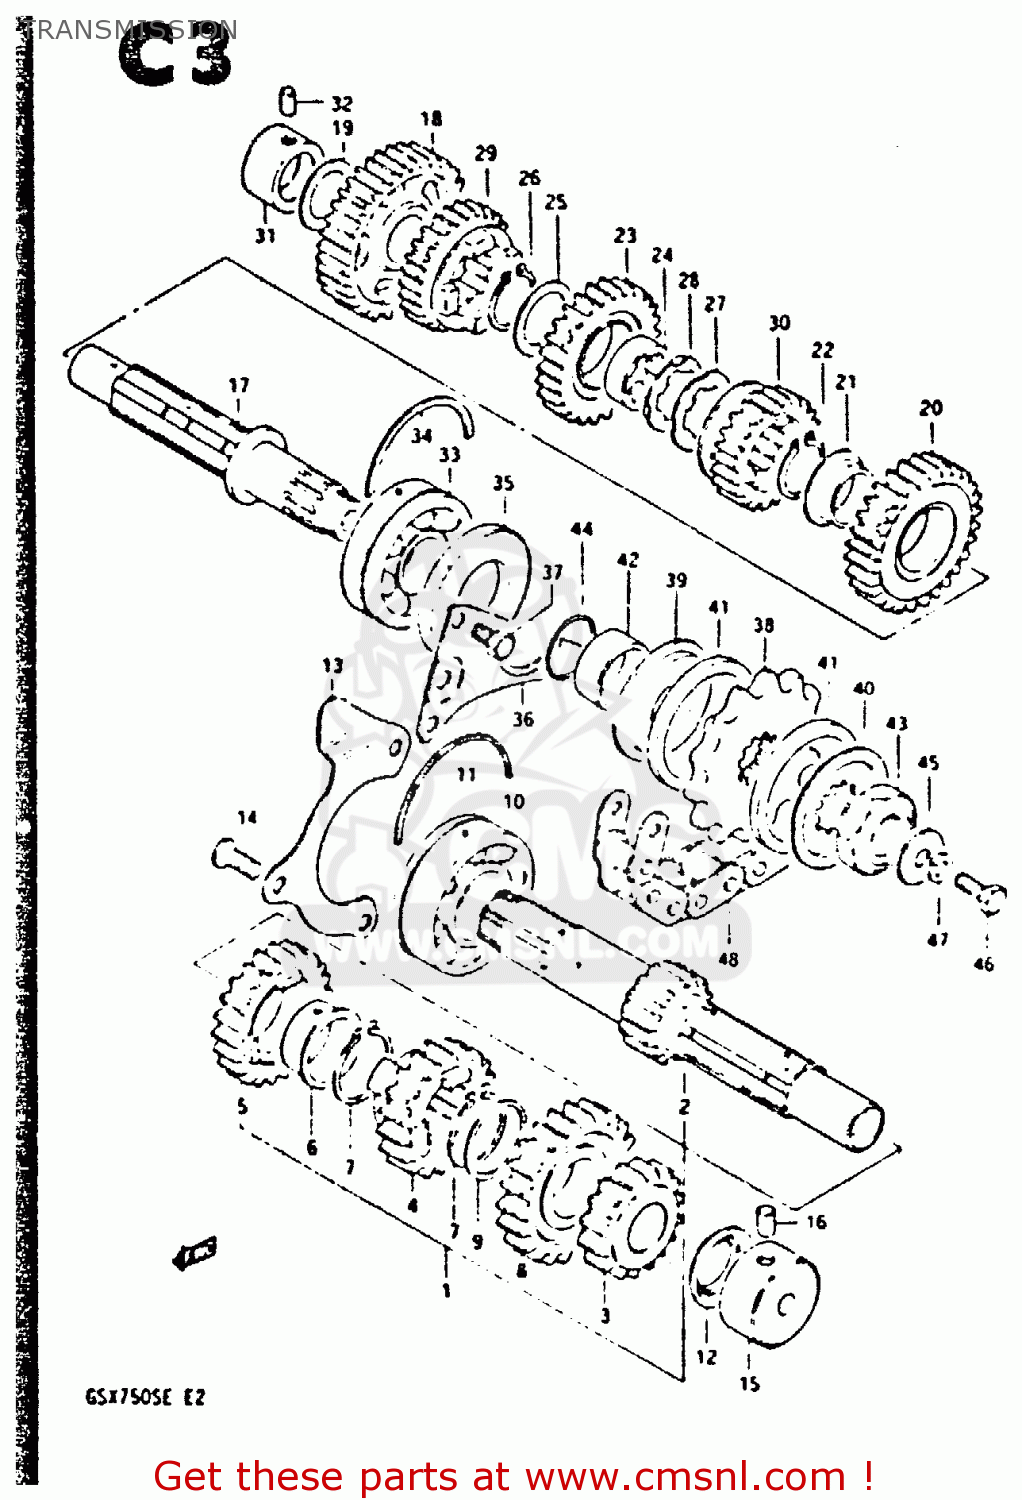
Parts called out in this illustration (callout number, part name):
1	SHAFT,COUNTER
2	SHAFT,COUNTER
3	GEAR,SECOND DRIVE
4	GEAR,THIRD DRIVE
5	GEAR,FOURTH DRIVE
6	BUSHING
7	RING,SNAP
8	GEAR,FIFTH DRIVE (NT:23)
9	WASHER,LOCK
10	BEARING(25X62X17)
11	C-RING
12	SEAL,OIL(20X31.2X2.7)
13	PLATE,COUNTERSHAFT BEARING
14	SCREW
15	BEARING(20X34X17.5)
16	PIN
17	SHAFT,DRIVE
18	GEAR,1ST DRIVEN(NT:35)
19	WASHER
20	GEAR,2ND DRIVEN(NT:28)
21	BUSH(28X32X2)
22	CIRCLIP
23	GEAR,THIRD DRIVEN
24	BUSH,3RD DRIVEN GEAR
25	WASHER,LOCK
26	CIRCLIP
27	WASHER,LOCK
28	WASHER
29	GEAR,4TH DRIVEN(NT:26)
30	GEAR,5TH DRIVEN(NT:22)
31	BEARING(20X34X20)
32	PIN
33	BALL BEARING 25X62X17
34	C-RING
35	SEAL,OIL(33X62X7)
36	PLATE,DRIVESHAFT OIL
37	BOLT
38	SPROCKET,ENGINE
39	HOLDER, SPROCKET, NO.1
40	HOLDER,SPROCKET DAMPER
41	DAMPER,SPROCKET
42	SPACER
43	NUT
44	O RING(D:1,ID:24.5)
45	WASHER
46	BOLT, UPPER
47	LOCK WASHER
48	CHAIN ASSEMBLY,DRIVE
